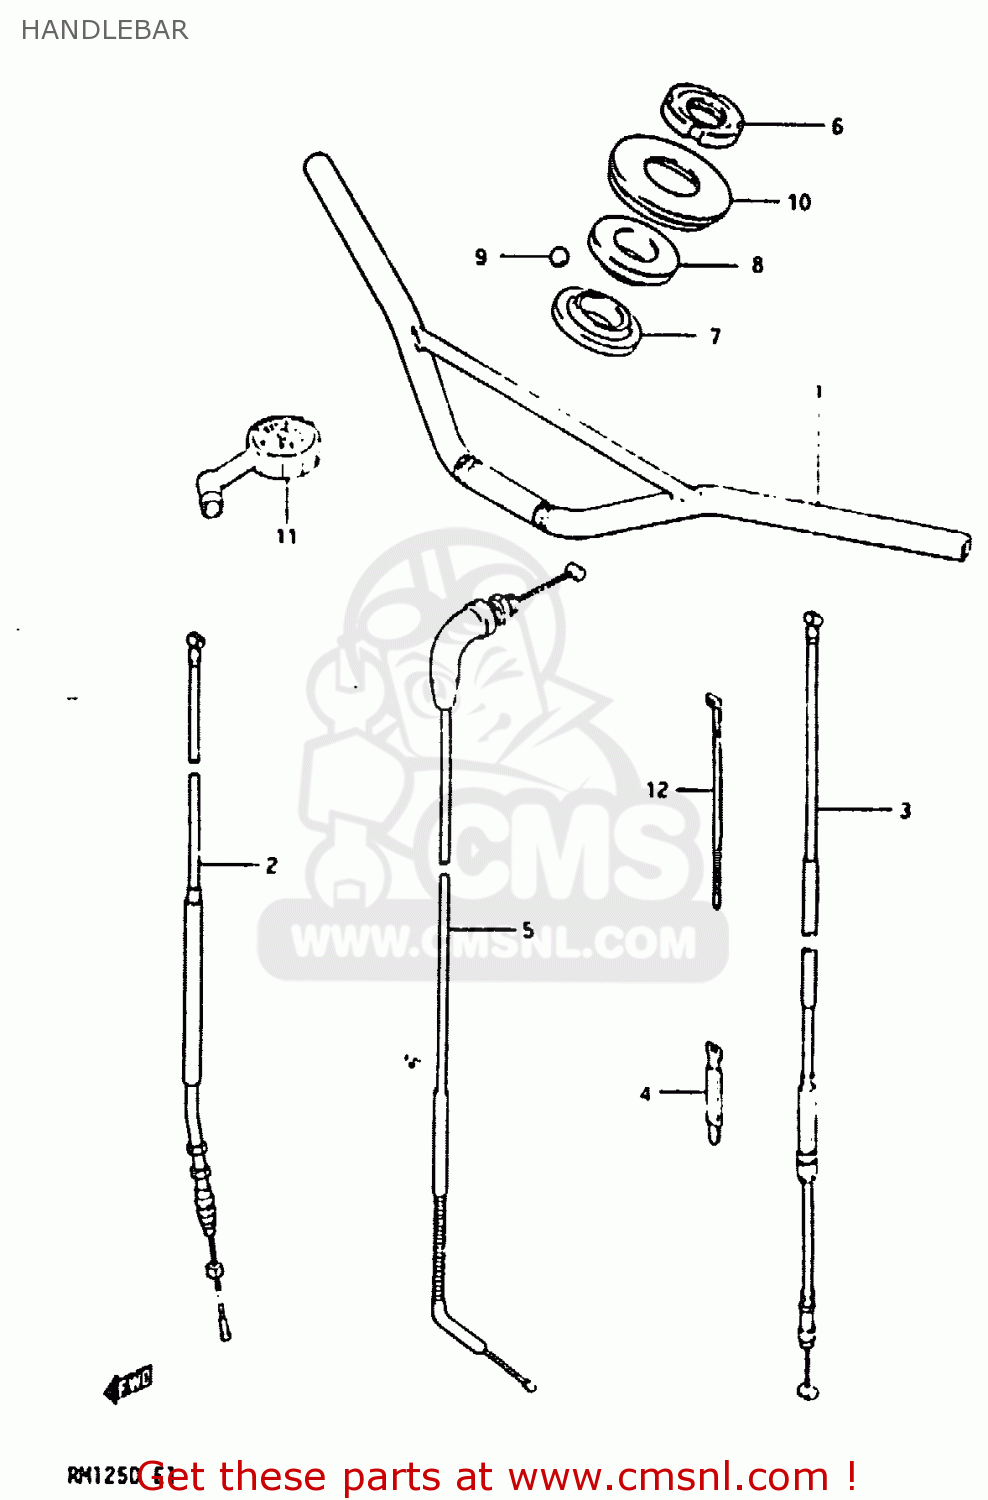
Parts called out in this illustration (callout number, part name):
1	HANDLEBAR
2	CABLE ASSY,FR BRAKE
3	CABLE ASSY,CLUTCH
4	CLAMP
5	CABLE ASSEMBLY,THROTTLE
6	NUT,STEERING STEM
7	RACE,STEERING,INNER,UPPER
8	RACE,STEERING,OUTER,UPPER
9	BALL
10	SEAL,STEERING UPR DUST
11	GAUGE ASSY,AIR PRESSURE
12	CLAMP
